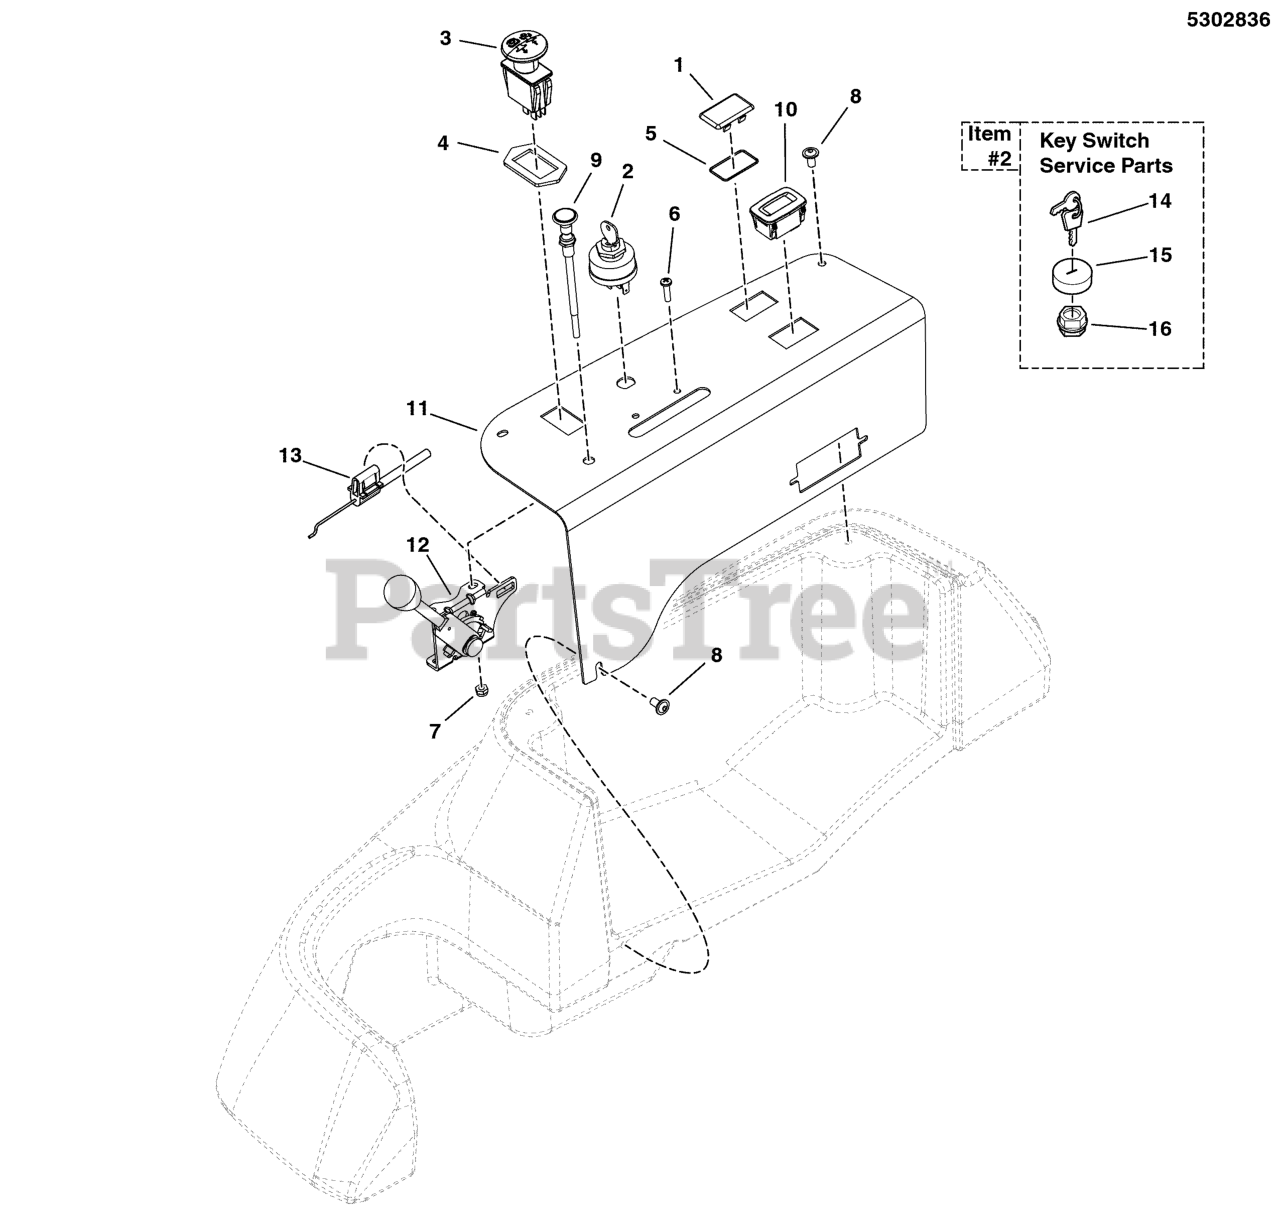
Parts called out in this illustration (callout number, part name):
1	PLUG, .820X1.44 HOLE, BLACK PLASTIC
2	SWITCH, IGNITION, 6 POST
3	SWITCH, BLADE ENGAGEMENT
4	RING, SWITCH RETAINER
5	O-RING, 7/8 ID X 1/16 W
6	SCREW, #10-24 X 3/4 ROUND PHILLIPS
7	NUT, #10-24 HEX NYLON LOCK
8	SCREW, 1/4-20 X 1/2 ALLEN BH
9	CABLE, CHOKE CONTROL, 47
10	HOUR METER, ASSEMBLE
10	HOUR METER
11	PLATE, CONTROL PANEL - BLK
11	PLATE, CONTROL PANEL, IS600Z
12	LEVER, THROTTLE CONTROL, HEAVY-DUTY
13	CABLE, THROTTLE, 42"
14	KEY, IGNITION MOLDED SET
15	COVER, PLASTIC, SNAP ON
16	PLASTIC NUT
